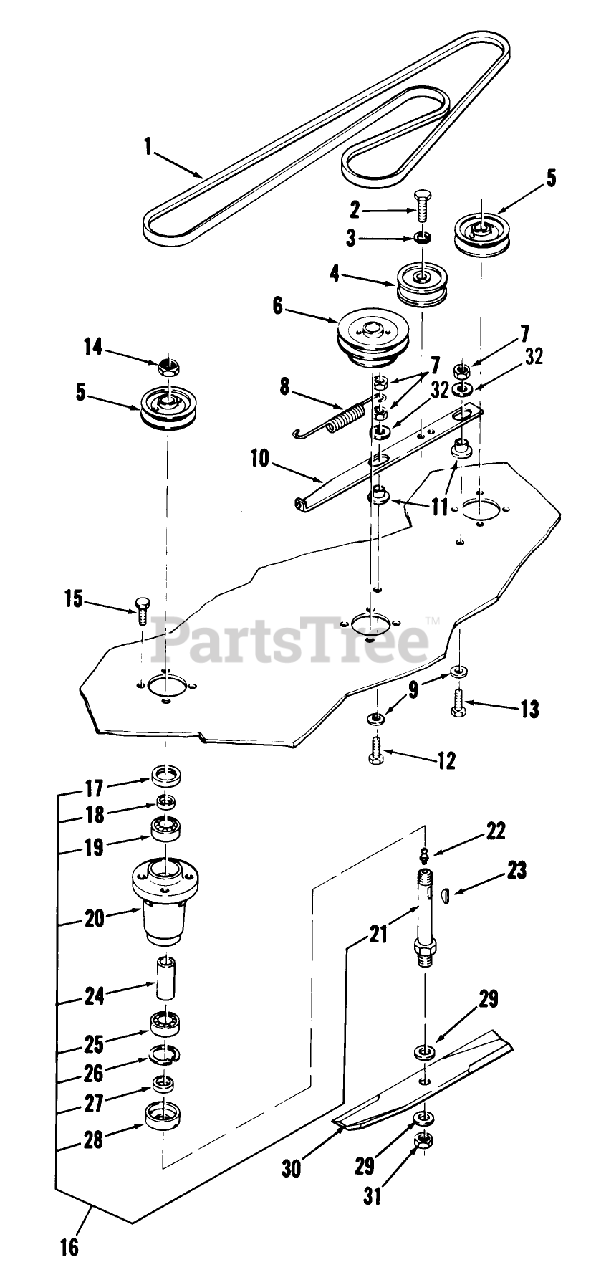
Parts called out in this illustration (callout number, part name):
1	V-BELT
5	PULLEY-BLADE DRIVE
6	PULLEY-48 MOWER SPDL
8	SPRING-EXTENSION
9	WASHER
10	BAR-IDLER SUPPORT
11	SPACER-BUSHING
18	SPACER-SEAL
19	BEARING-BALL
23	Hi-Pro Key 3/16 x 5/8
24	SPACER
25	BEARING-BALL
26	Ring-Snap
27	SPACER-BLADE
29	SpeciaI Washer
30	BLADE KIT (3 PACK)
32	WASHER
